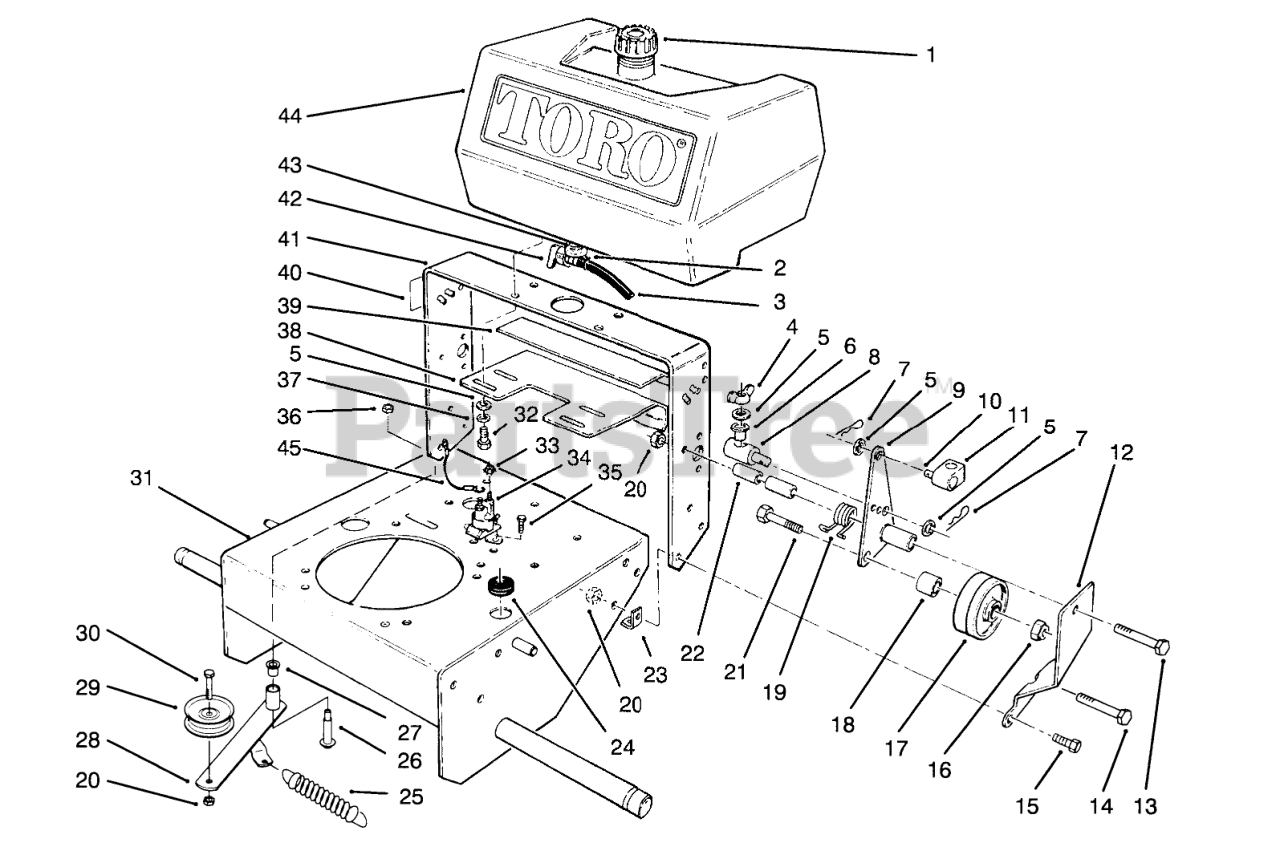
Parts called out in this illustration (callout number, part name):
1	GAS CAP ASM
2	CLAMP-HOSE
3	HOSE-FUEL
4	NUT-WING
5	WASHER-PLAIN
6	BUSHING-NYLON
7	FITTING-ROD
8	PIN-COTTER
9	BRACKET-Idler, LH
10	PIN-CLEVIS
11	FITTING-ROD
12	Bracket-LH
13	SCREW-HH
14	SCREW-HH
15	SCREW-HH
16	NUT-LOCK, NI
17	IdlerWheel
18	WHEEL IDLER SPACER
19	SPRING-TORSION, LH
20	NUT-LOCK, NI
21	SCREW-LEVELER
22	SPACER-PIVOT, IDLER
23	ANCHOR SPRING R
24	GROMMET
25	SPRING
26	BOLT-WHEEL
27	BUSHING-FLANGE
28	LEVER-IDLER
29	PULLEY
30	SCREW-HH
31	FRAME
32	SCREW-HH
33	NUT-KEPS
34	SOLENOID
35	SCREW
36	NUT-LOCK
37	WASHER-LOCK
38	Plate
39	DECAL-GROUND SPEED
40	DECAL-FUEL SHUT OFF
41	Frame Rear
42	VALVE-FUEL
43	O-RING
44	FUEL TANK
45	WIRE-SOLENOID/STARTER
